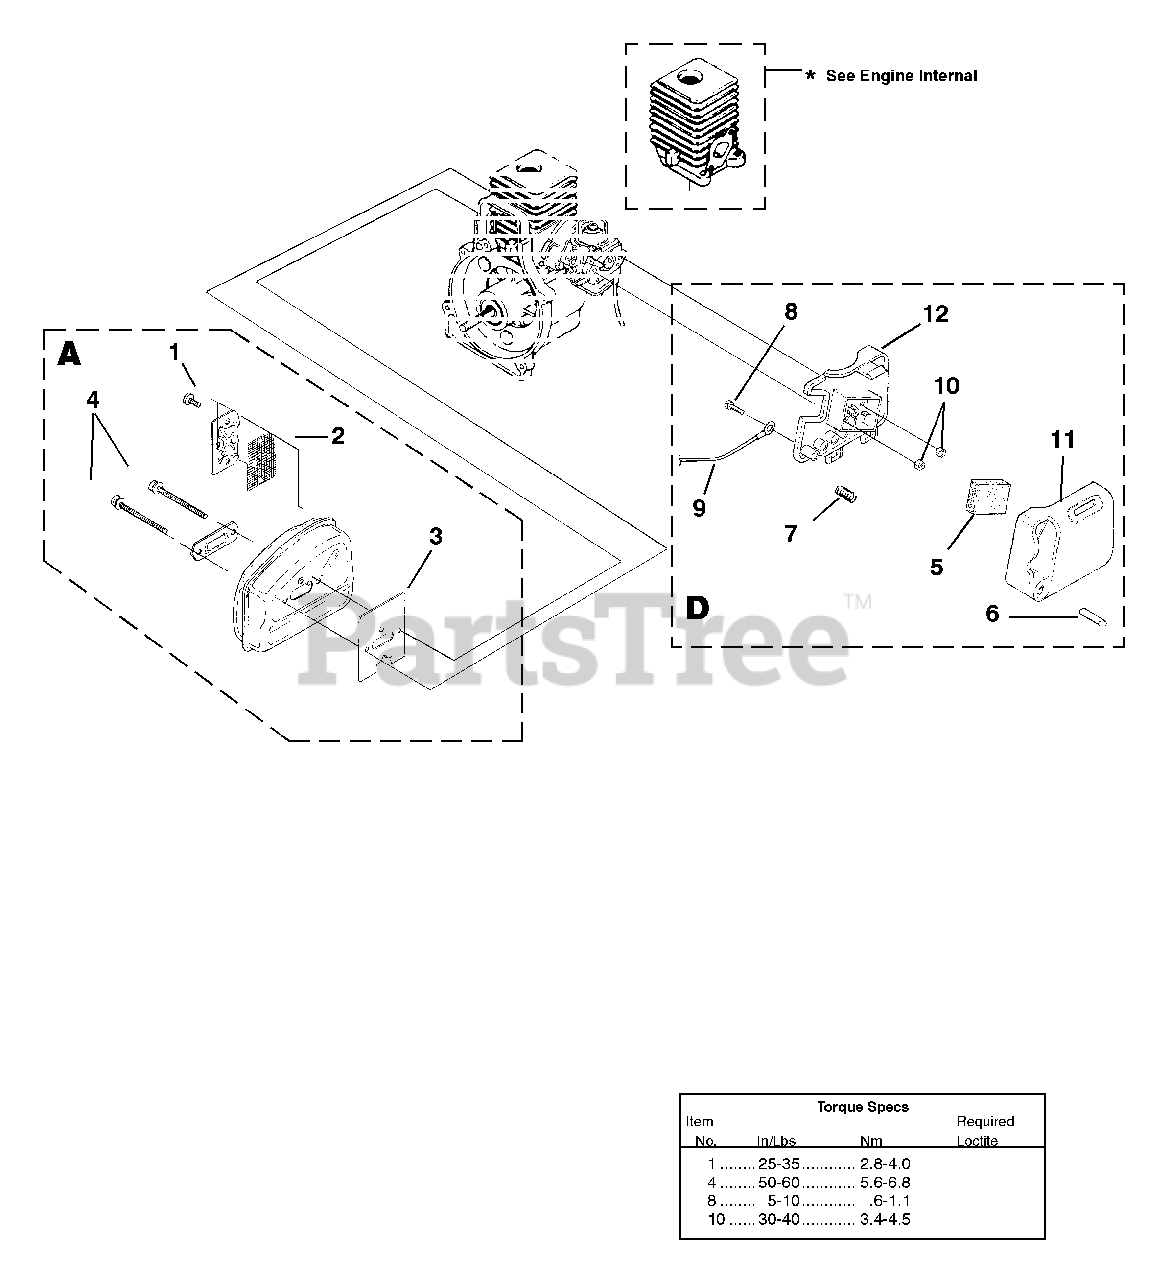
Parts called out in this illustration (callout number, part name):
1	SCREW, Taptite- (8-32 X 3/8")
2	SCREEN-Spark
3	GASKET-Muffler
4	SCREW, Truss Hd. - (10-24 X 2.188)
5	FILTER-Air
6	BUTTON-Switch
7	SPRING-Compression
8	SCREW-Thread Form (6-19 x 1/2")
9	LEAD-Electrical
10	NUT-Hex (10-24)
11	AIR FILTER BOX
12	COVER AIR BOX
A	MUFFLER ASSY.
D	AIR FILTER KIT
